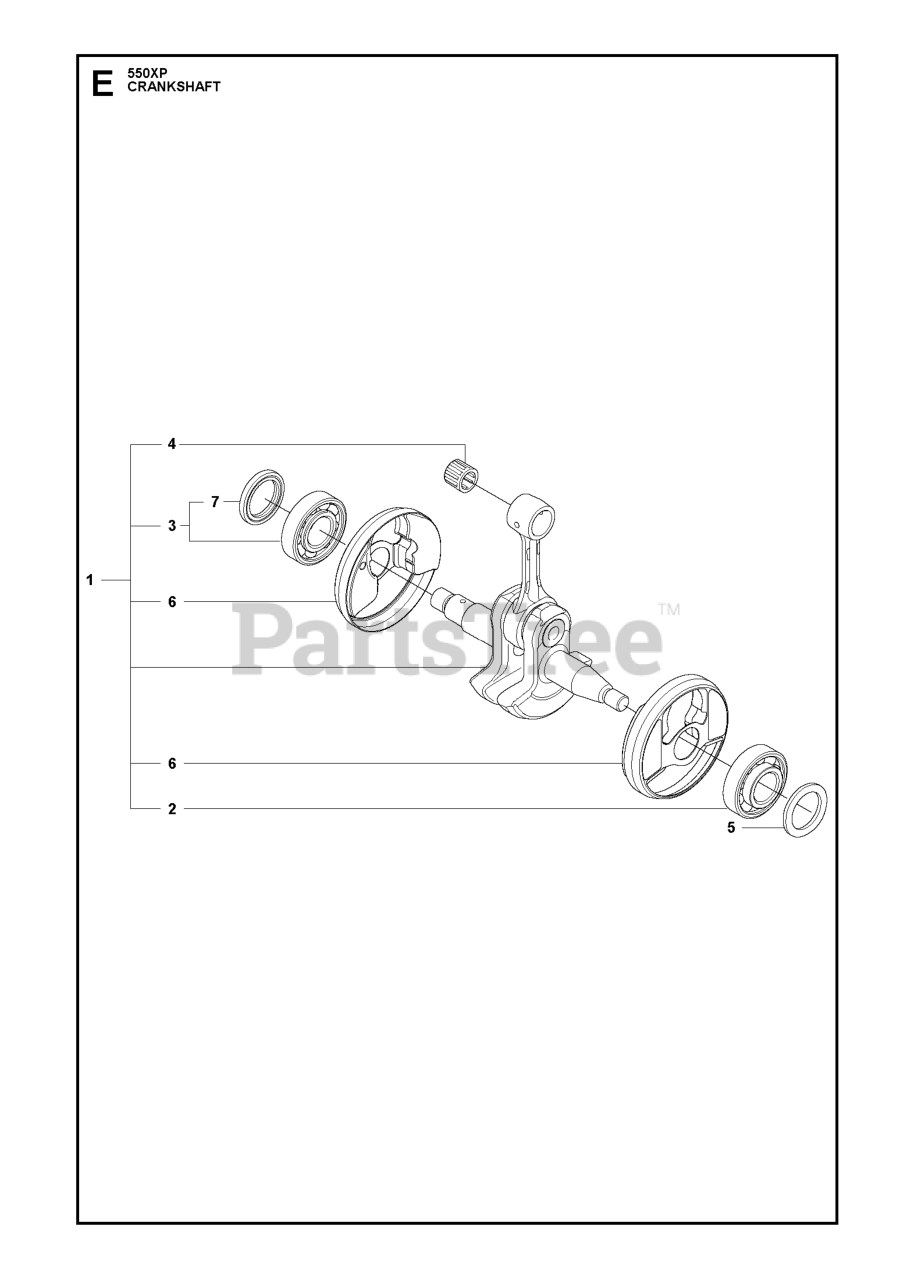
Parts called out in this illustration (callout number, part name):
1	CRANKSHAFT ASSY
2	BALL BEARING
3	BALL BEARING
4	SUPPORT BUSHING
5	RADIAL SEAL
7	RADIAL SEAL
